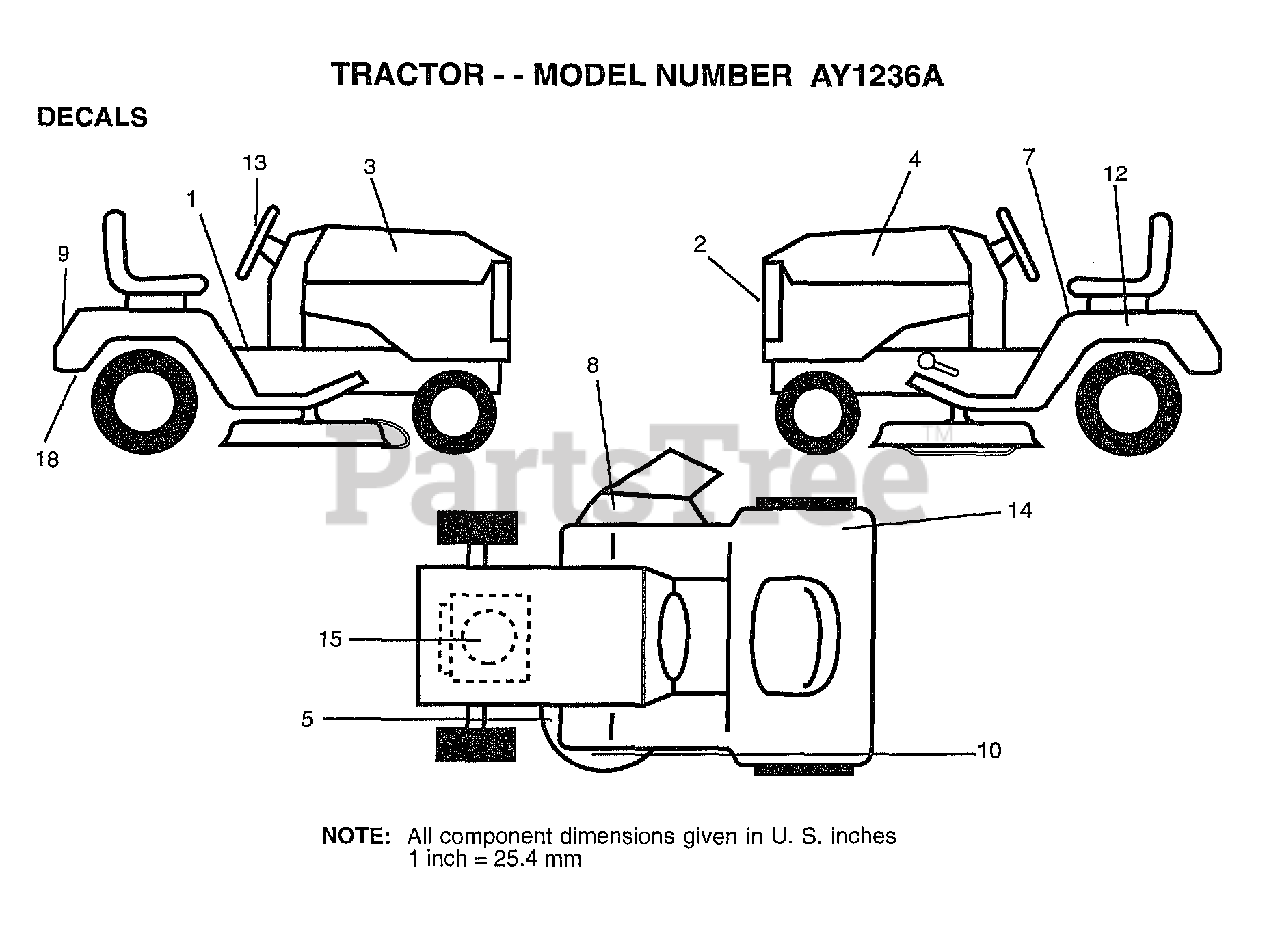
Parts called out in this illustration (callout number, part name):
1	DECAL.OP.INST.SYM
2	"DECAL,LIGHT BOX"
3	DECAL HOOD RH
4	DECAL HOOD LH
5	DECAL.V.BELT
7	DECAL.READ.O.MANU
8	DECAL.DANGER.CUTF
9	"DECAL,FENDER"
10	DECAL DECK WIZ +
12	DECAL.BTRY.DANGER
13	"DECAL,INSERT"
15	DECAL, ENGINE
18	DECAL.EURO.ST.CE.
